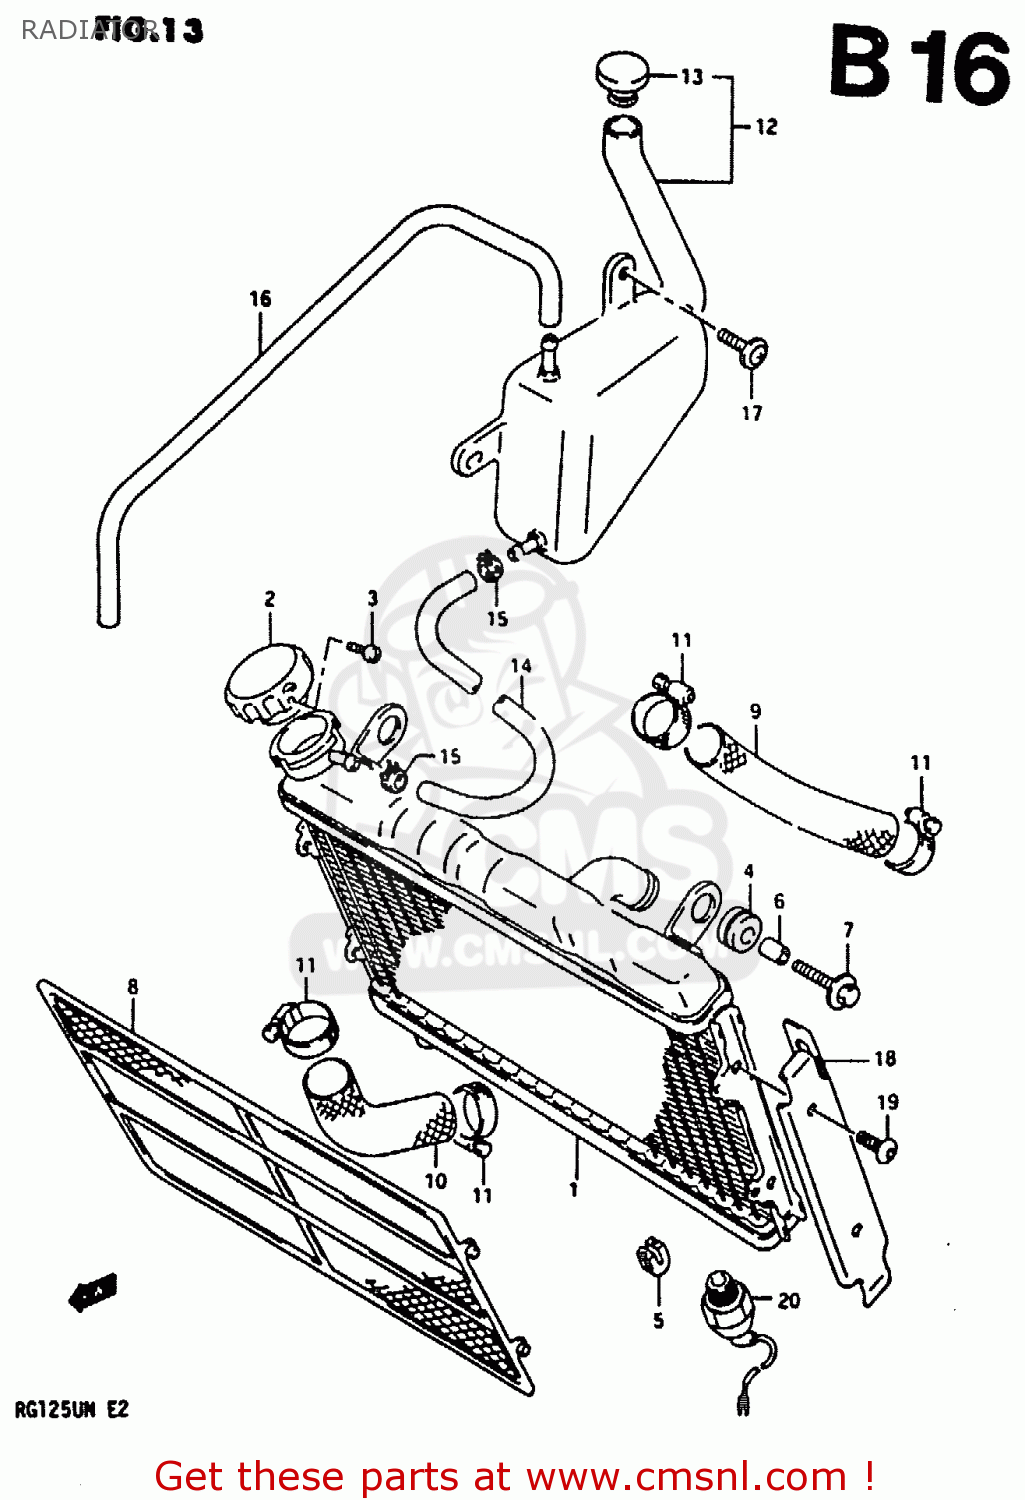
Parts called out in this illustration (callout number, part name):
1	RADIATOR, WATER
2	CAP COMP,RADIATOR 1.1
3	SCREW,RADIATOR CAP
4	CUSHION
5	CUSHION,OIL COOLER NO.2
6	SPACER (6.8X10X12)
7	BOLT(6X25)
8	NET,RADIATOR
9	HOSE, RADIATOR, INLET
10	HOSE,RADIATOR
11	CLAMP
12	TANK,RESERVOIR
13	CAP,RESERVOIR TANK
14	HOSE(5X9X2000)
15	CLIP
16	HOSE
17	SCREW(6X20)
18	COVER, RADIATOR
19	SCREW(6X12)
20	SWITCH ASSY,WATER TEMP
